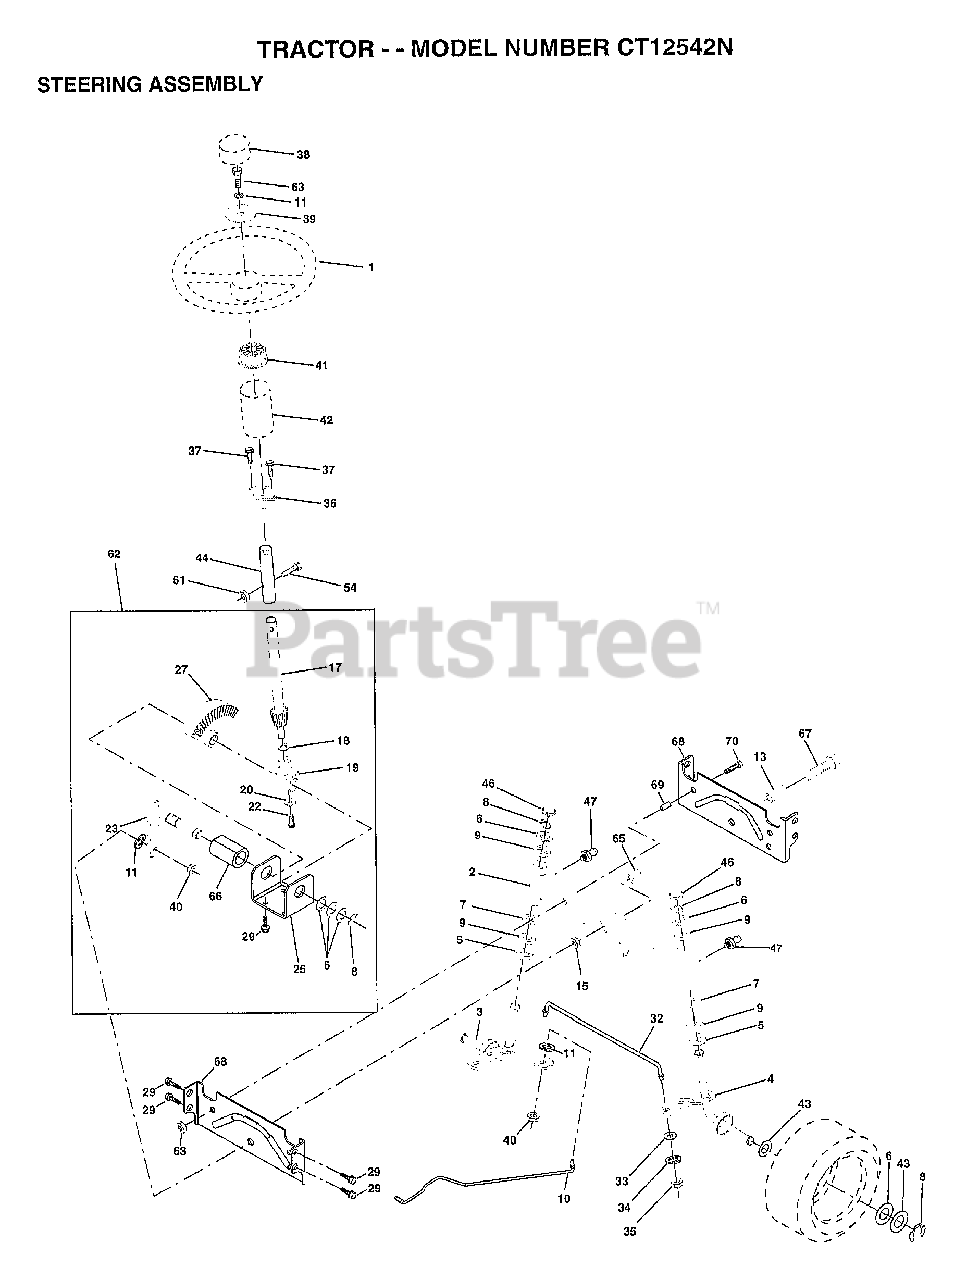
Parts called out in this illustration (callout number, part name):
1	WHEEL STR AYP BLK
2	AXLE ASM
3	SPINDLE.ASM.LH
4	"SPINDLE ASM,RH"
5	WASHER .T
6	WASHER
7	WASHER
8	RING
9	COL. SRTG. BEAR.
10	DRAGLINK-STAMPED
11	LOCKWASHER
13	BEARING AXLE
15	"NUT-LOC,FLANGE LT"
17	SHAFT ASM STEERIN
18	THRUST WASHER
19	SUPPORT.SHAFT
22	SCREW HEX SOC1/4-
25	BRKT-STEERING
27	GEAR SECTOR
29	SCREW
32	ROD.TIE.19.75
33	WASHER M
34	LOCKWASHER
35	NUT.LOCK.5/16-24
36	BUSHING.STEERING
37	"SCREW-TT,10-32 FL"
38	CAP STEER AYP
39	WASHER T
40	GRIPCO NUT
41	ADAPTER LT
42	BOOT.STEER.PL
43	WASHER
44	EXT SHAFT STEERIN
46	CAP
47	ZERK M
51	NUT
54	BOLT
62	KIT STEERING ASM
63	BOLT
65	SPACER AXLE
66	"BEARING-ARM,PITMA"
67	BOLT
68	BRACE AXLE
69	"SPACER BRCAE,AXLE"
70	BOLT.HEX.3/8-16X2
